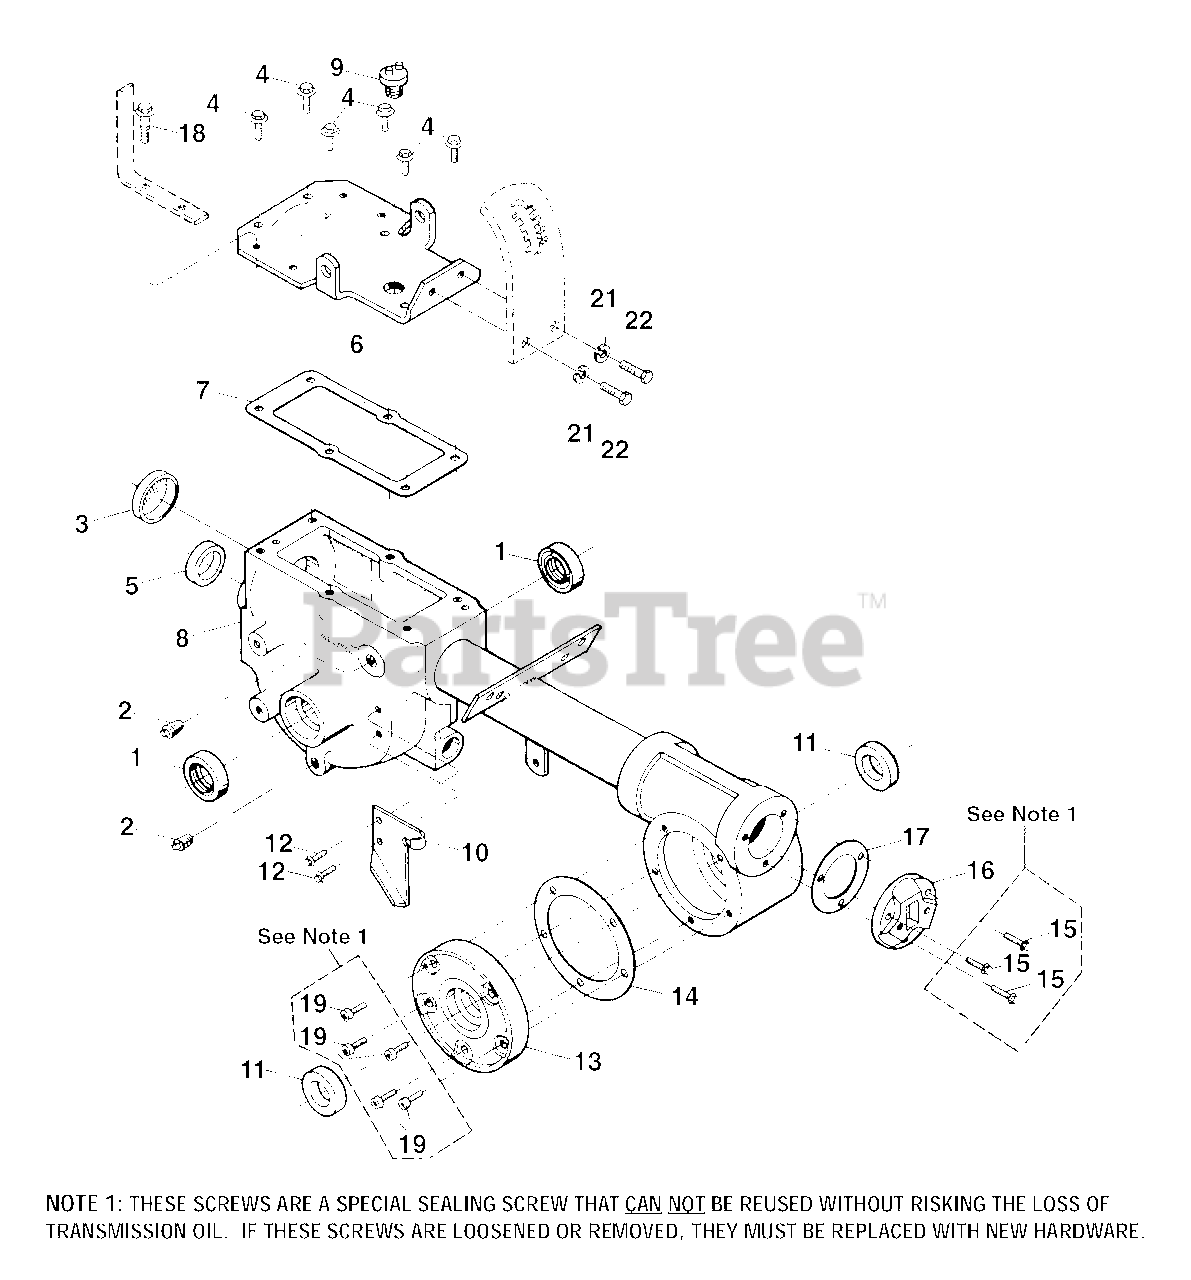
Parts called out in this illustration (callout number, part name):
1	Oil seal, wheel shaft, left and right sides
2	Plug, pipe,1/4
3	Seal, transmission bore
4	Screw, flanged hex hd., 5/16-18 x 3/4
5	Oil seal, input pinion shaft
6	Transmission cover, top
7	Gasket, top cover
8	Transmission case, tube & rear housing assembly
9	Plug
10	Plate, wheel drive cable mounting
11	Oil seal, tiller shaft, left and right sides
12	Screw, flanged hex hd., 5/16-18 x 5/8
13	Cover, left side
14	Gasket, cover, .010 thick (fits all covers)
15	Screw Kit
16	Cap, rear bearing
17	Gasket, rear bearing cap, .010 thick
18	Screw, flanged hex hd., 5/16-18 x 1
19	Screw Kit
21	Lockwasher, 3/8
22	Screw, hex hd., 3/8-16 x 3/4
